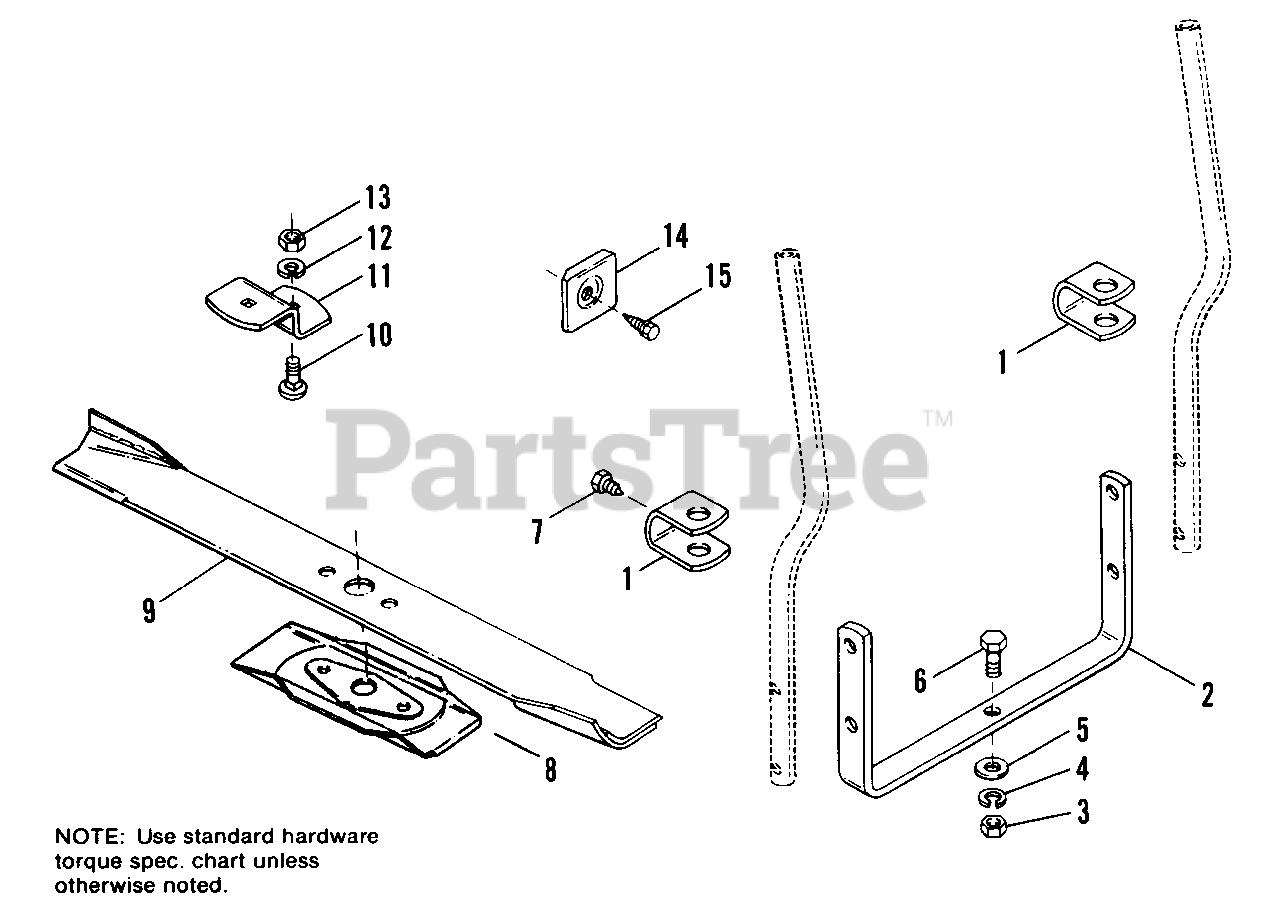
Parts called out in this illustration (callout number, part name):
2	SUPPORT, Bracket
3	NUT, Hex, Full, 3/8-16
4	LOCKWASHER, 3/8
5	WASHER, Plain, 3/8
6	CAPSCREW, Hex Hd., 3/8-16 x 1
7	SCREW, Thd. Cutting, Rd. Hd., 1/4-20 x 3/8
8	STIFFENER, Blade
9	BLADE ASSY.
10	BOLT, Carriage, 5/16-18 x 5/8
11	SUPPORT, Adaptor
12	LOCKWASHER, 5/16
13	NUT, Hex, Full, 5/16-18
14	DEFLECTOR, Muffler
